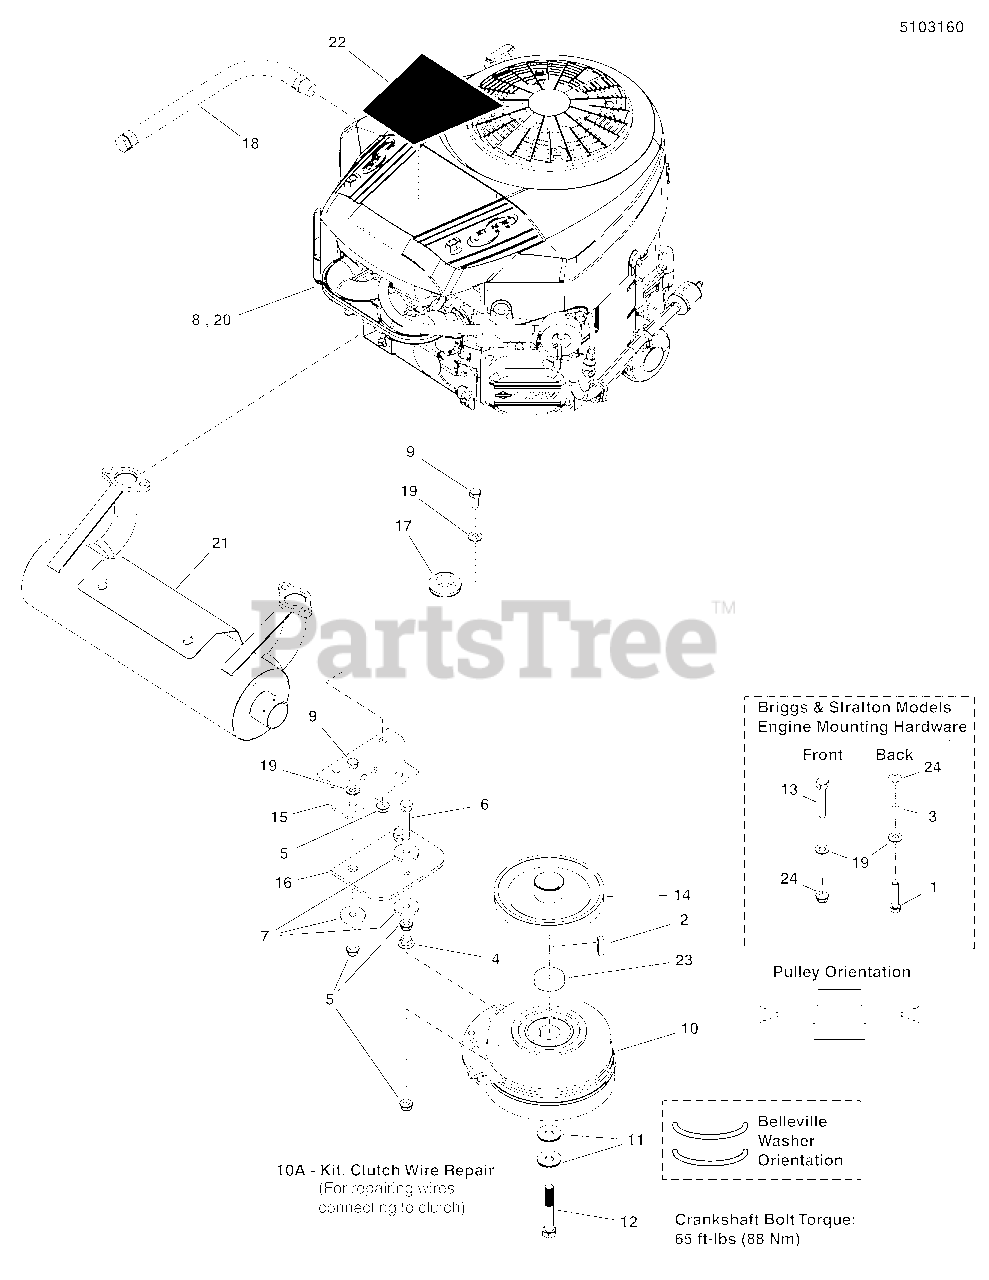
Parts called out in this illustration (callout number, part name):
1	BOLT-HEX, 5/16-24 X 1-1/2", GD8, PHOS
2	KEY, 1/4 Square x 1
3	WASHER, 5/16" Internal Tooth Lock
4	NUT, 5/16-18 HEX SERRATED FLANGE (LARGE)
5	NUT, Ny Lock Flange, 5/16-18
6	BOLT, 5/16-18 X 2" GD 5 TFL
7	WASHER, CLUTCH ANCHOR, 5/16
9	CAPSCREW, Hex Head, 5/16-18 X 1
10	CLUTCH, WARNER, 200 FT-LB, 1.13" X 6.323
10A	KIT, CLUTCH WIRE REPAIR
11	BELLEVILLE, WASHER, 1.1875 X .442 X .089
12	BOLT, CRANKSHAFT,7/16-20X2-3/4, GD8
13	BOLT, 5/16-24 X 1-3/4, GD8, PHOS
14	PULLEY,CRANKSHAFT,1.125ID X 5.5OD A SECT
15	ANCHOR, CLUTCH, IS600-IS700 - BLK
16	PAD, Clutch Anchor
17	GROMMET, 7/8"
18	HOSE, OIL DRAIN
19	WASHER, 5/16
21	MUFFLER, RIGHT OUTLET ASSY
22	LABEL, POWER
23	SPACER, 1.13 X 1.75 X 1.03, CZ
24	NUT, 5/16-24, TOP LOCK FLANGE, GD8 PHOS
